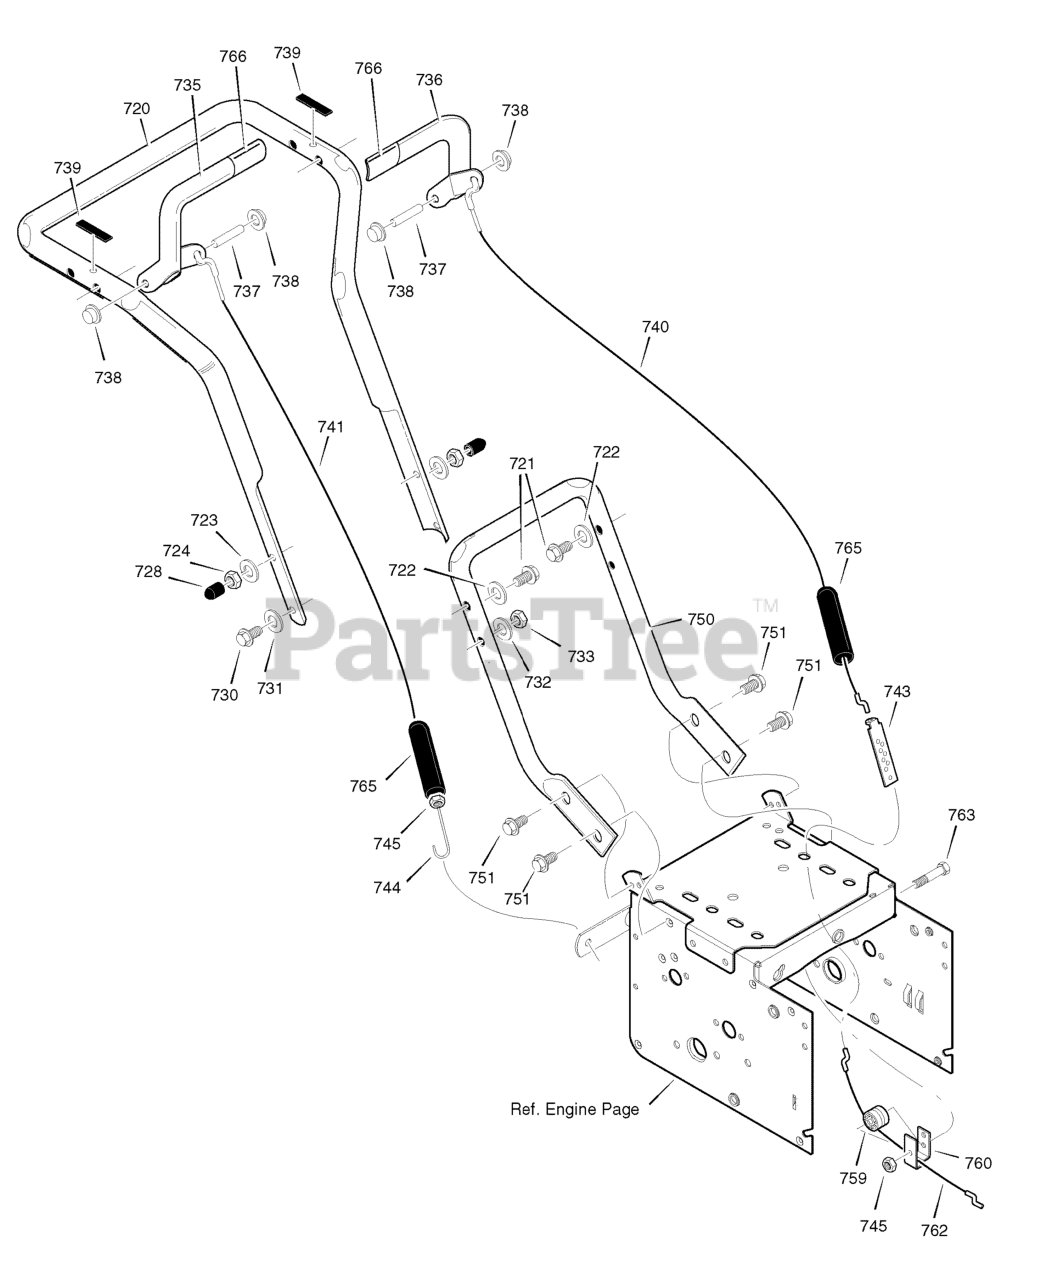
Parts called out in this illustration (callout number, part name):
720	HANDLE, UPPER
721	SCREW, 3/8- 16 X 3
722	WASHER, Flat, 13/32
723	WASHER
724	NUT, 3/8- 16
728	STOP, PLASTIC
730	SCREW, 3/8- 16 X 2
731	WASHER, Flat, 13/32
732	WASHER
733	NUT, 3/8- 16
735	HANDLE, RIGHT
736	HANDLE, LEFT
737	PIN, PIVOT CLUTCH
738	NUT, PUSH ON CAP
739	BUMPER, RECTANGLE
740	CABLE, DRIVE
741	CABLE, AUGER CLUTCH
743	BRACKET, CABLE ADJUSTER
744	SPRING, AUGER CLUTCH
745	NUT, 1/4- 20
750	HANDLE, LOWER
751	SCREW, TAP 5/16-18 X .75
759	SPOOL-CABLE, AUGRT CLUTCH
760	BRACKET, CABLE SPOOL YZ
762	CABLE, LOWER DRIVE 12"
763	BOLT, HEX 1/4-20 X 1.5
765	BOOT, CLUTCH SPRING
